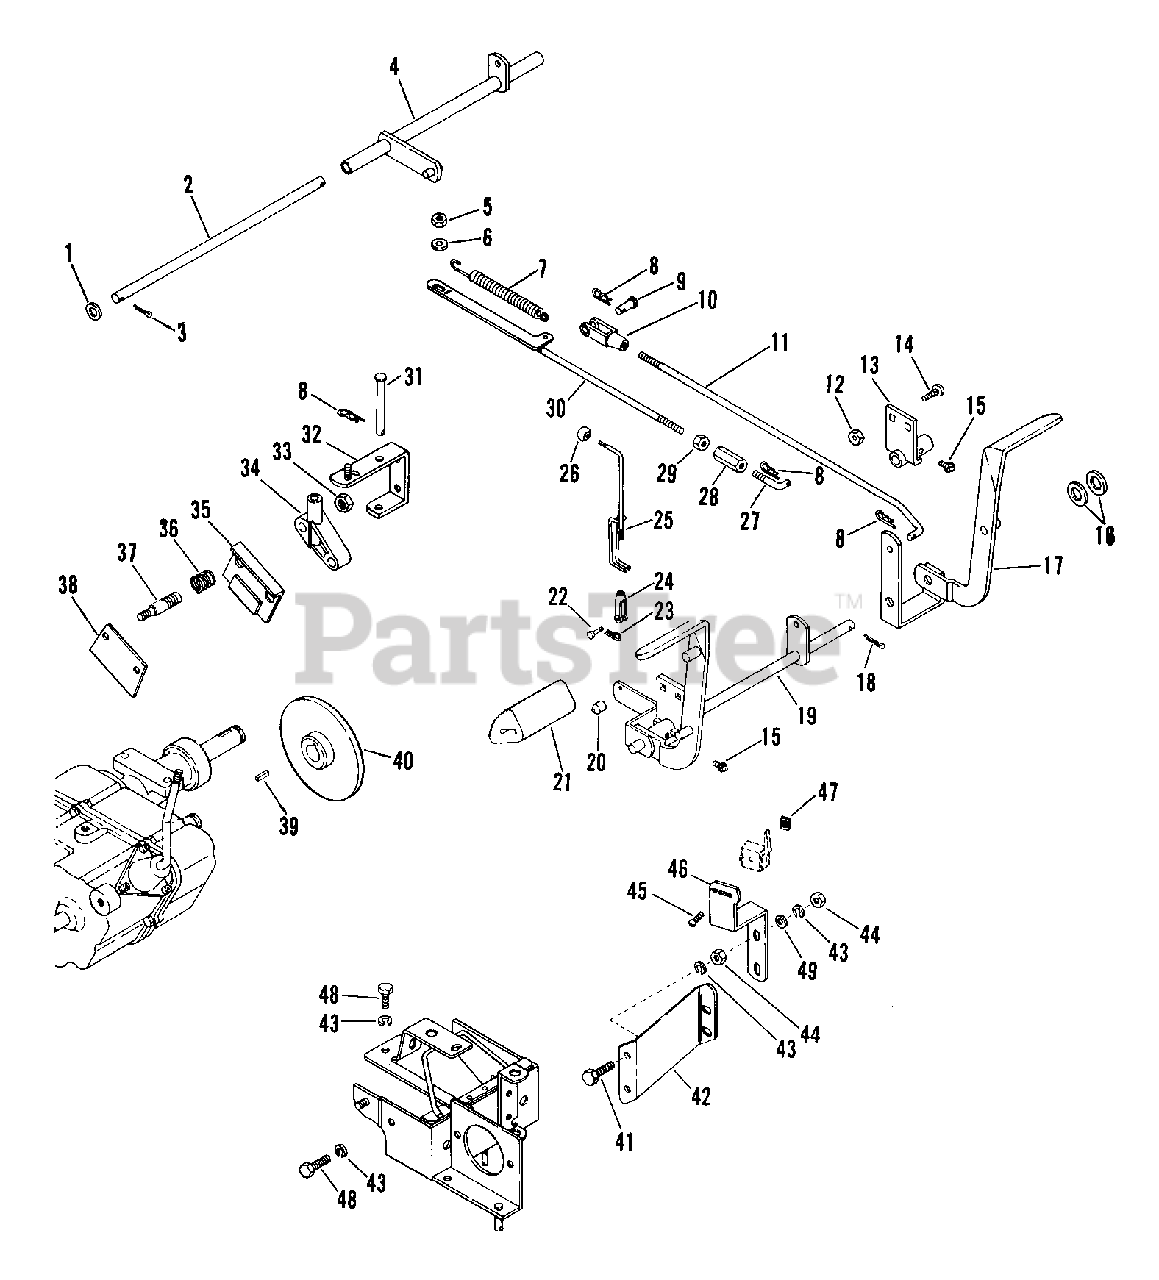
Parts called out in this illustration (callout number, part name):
1	WSHR-FL-STL .531X1.062X.095 PL
2	PIVOT SHAFT
3	PIN-COTR .12X1.0 PL
4	ACTUATING PIVOT
4	CLUTCH PIVOT
5	NUT-LK .312-18 GR A PL
6	WSHR-FL-STL .328X.875X.062 PL
7	SG-TENS .135X.69X5.75 WLD 150
8	PIN-HAIR INT .08X.18X1.18
9	PIN-CLEV .373X1.12 YWZC
10	YOKE, .375-24 X 2.50
11	CLUTCH ROD
12	NUT-FLG. .312-18 PL
13	PEDAL PIVOT L H
14	BLT-RDHDSQNK .31-18X.75 GR5 PL
15	SPIN DRIVE ZERK FITTING
16	WSHR-FL-STL .699X1.375X.059
17	CLUTCH PEDAL
18	PIN-COTR .18X1.25 PL
19	BRAKE PEDAL
21	PEDAL COVER
22	@ CLEVIS PIN
23	PIN-HAIR INT .06X.18X.77
24	YOKE, .190-32 X 1.563
25	PARKING BRAKE ROD
28	NUT-CUPLG RH & LH THD .37-16PL
29	NUT-JAM .375-16 PL
30	BRAKE ROD
31	CLEVIS PIN
32	ACTUATOR
33	NUT-LK-NYL.625-18 PL
34	ACTUATOR MOUNT
35	BRAKE PAD
36	SG-COMP .068X.85X.75 WLD11
38	BRAKE PAD
39	KEY-WDRF .188X.75X.313 SAE 9
40	DISC
41	BLT-HEX .38-16X1.50 PL GR2
42	TORQUE STRUT
43	WSHR-LK .375X.115 HVY PL
44	NUT-HEX .375-16
45	SCR-MCH 10-24X1.00 SLRH PL
46	PTO INTERLOCK SWITCH BRACKET
47	NUT-KEPS 10-24 PL
48	BLT-HEX .38-16X.75 PL GR5
49	WSHR-FL-STL.406X.812X.065PL
